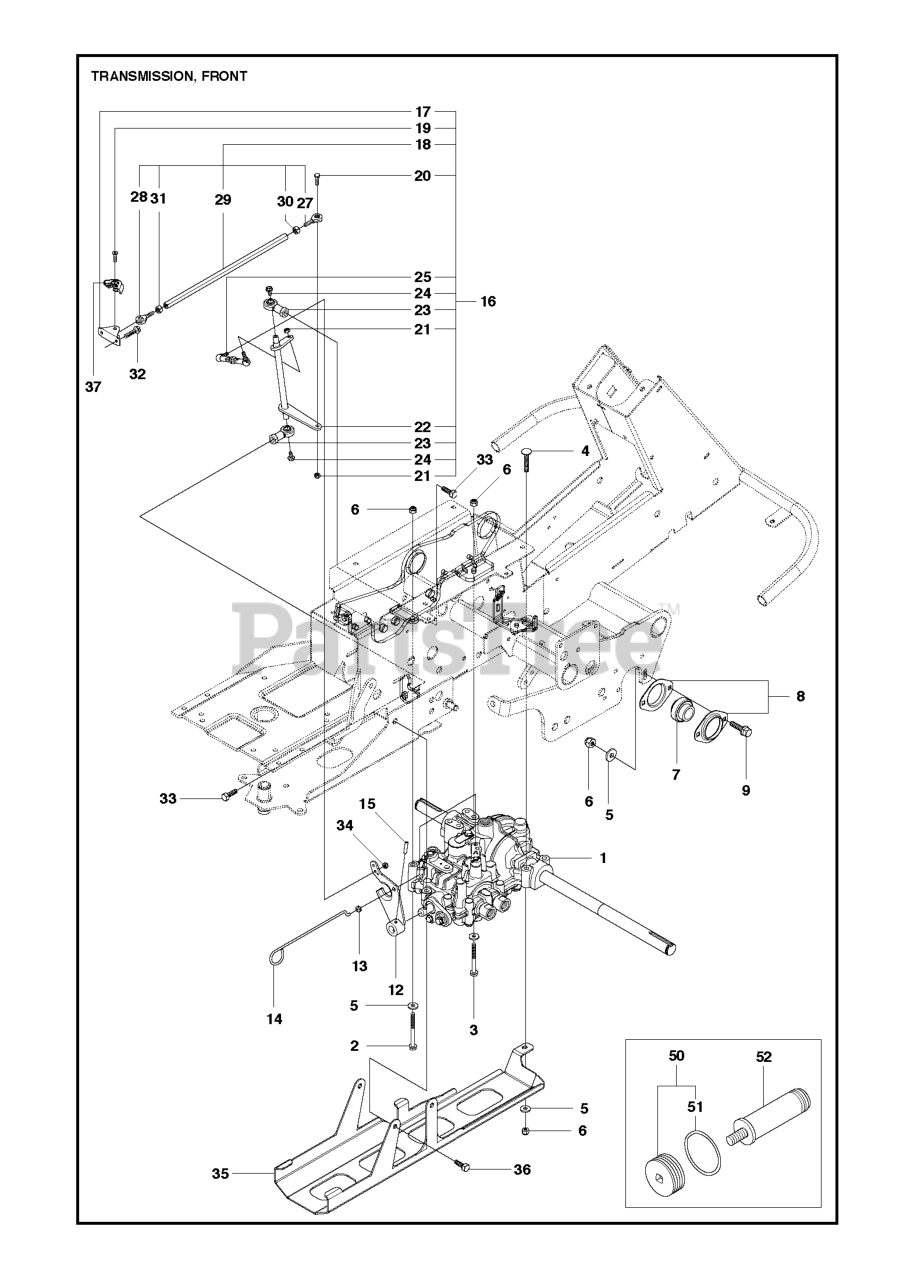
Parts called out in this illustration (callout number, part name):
1	TRANSMISSION
5	WASHER BRB 8.4X17
6	LOCKNUT M8
8	BEARING HOUSING
9	BOLT
13	FUEL TANK BUSHING
20	SCREW EHHM
21	LOCKNUT M6
24	SCREW EHHFM
25	ADJUSTING ROD
33	Screw M10x25
34	LOCKNUT M6
52	FILTER
